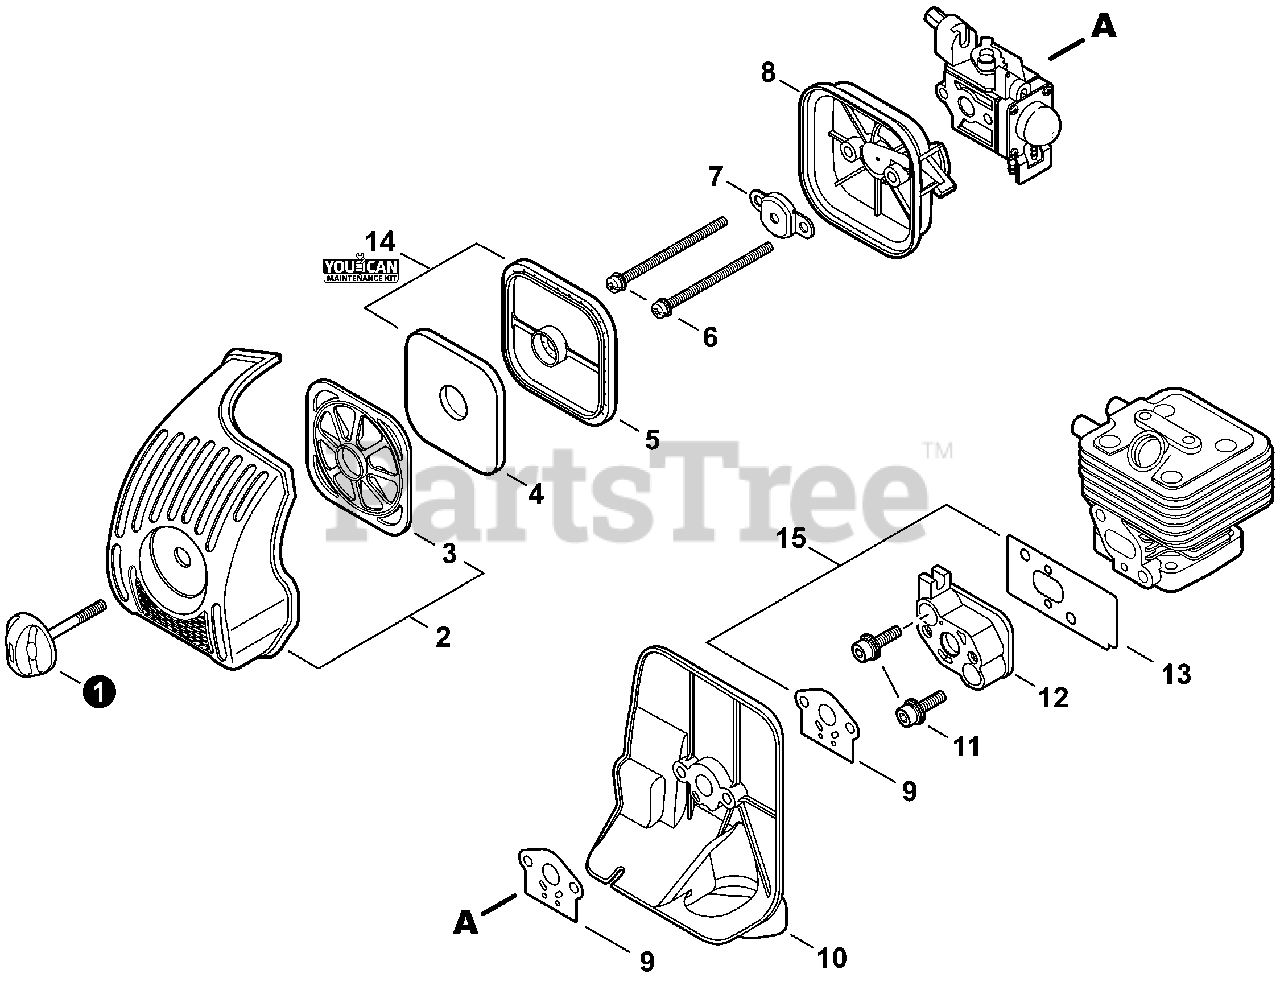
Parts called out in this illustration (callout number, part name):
1	THUMBSCREW
2	COVER KIT, AIR FILTER
3	RETAINER, PRE-FILTER
4	PRE-FILTER, FOAM
5	FILTER, AIR - DOUBLE LAYER
6	SCREW 5x70
7	PLATE, PREVENT
8	CASE, AIR FILTER
9	GASKET, INTAKE
10	PLATE, INSULATOR
11	BOLT 5x25
12	INSULATOR, INTAKE
13	HEAT SHIELD, INTAKE
14	TUNE-UP KIT - YOUCANT
15	GASKET KIT
